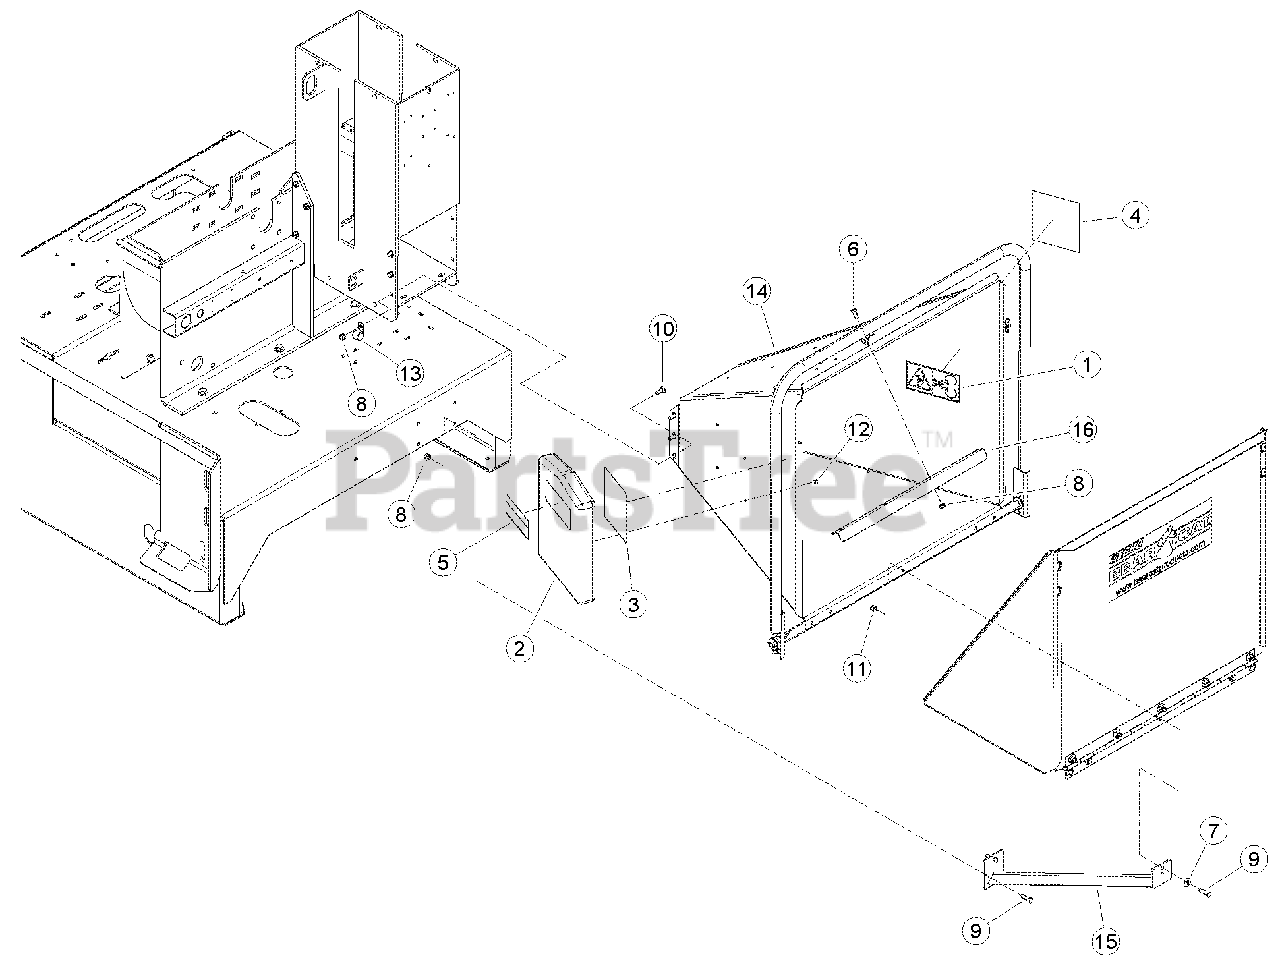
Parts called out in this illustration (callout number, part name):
1	DECAL, BLADE DANGER ISO
2	CONTAINER, INSTRUCTION MANUAL
3	DECAL, FEED POSITION
4	DECAL, FEED POSITION
5	DECAL, MUTILINGUAL MANUAL
6	BOLT 3/8 X 3/4 HEX HD GR5 ZP
7	WASHER, 3/8 FLAT ZP
8	NUT, 3/8 SERR FLANGE NC ZP
9	BOLT, 3/8 X 1-1/4 HEX HD GR5 ZP
10	BOLT, 3/8 X 1-1/4 CRG GR5 NC ZP
11	NUT, 3/8 NE NYLOCK ZP
12	RIVET, AL BLIND 1/4 X 1/2 DOME HEAD
13	CLAMP, 1" COATED METAL
14	ASSEMBLY, BIG CHIPPER CHUTE SERVICE PART
15	WELDMENT, CHUTE SUPPORT
16	ANGLE, CHUTE BRACE
